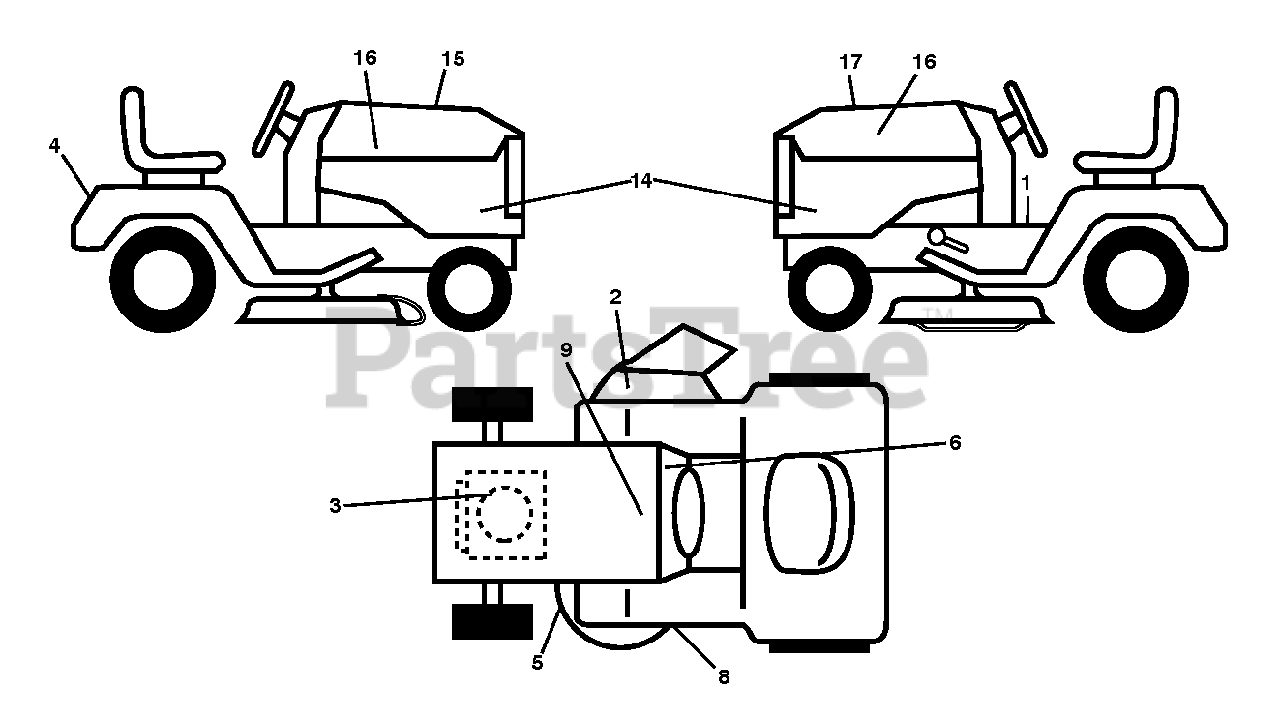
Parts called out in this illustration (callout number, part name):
1	DECAL.WARN.STARTINST.LOWEARIEN
2	DECAL.MOWER.WARN.KEEP.HAND.AWY
3	DECAL.ENG.BS.INTK.24HP.382016
4	DECAL.FENDER
5	DECAL.MOWER.CAUTION.TENSION.AR
6	DECAL.SNOWFLAKE.MS498.HUSQ
8	DECAL.MOWER.SCH.48/54.PREM
9	DECAL BTRY SYMBOLS
14	DECAL SIDE PANEL
15	DECAL.WARNING.CUST.RESP.E85.
16	DECAL.BADGE.170MM.TEXTLOGO.
17	DECAL.RPL.BSM44.INTK.TLW.48K57
18	DECAL.E85.WARNING.2012
19	DECAL.BYPASS.FENDER.CRD/LT/YT
20	PAD.FOOT.LH
21	PAD.FTRST.RH
